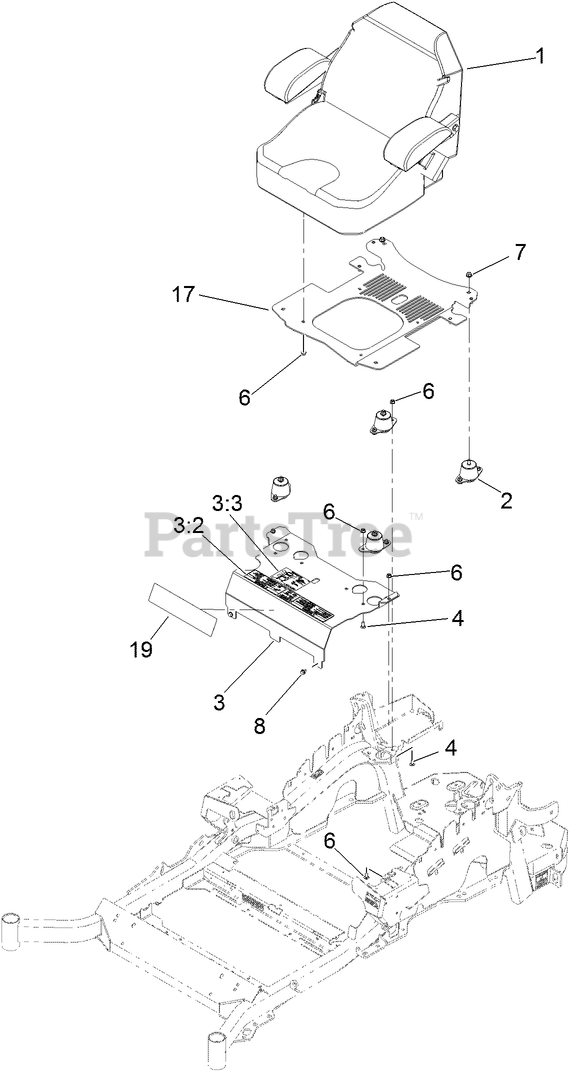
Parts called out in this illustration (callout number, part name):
1	SEAT-STANDARD
2	ISOLATOR-SEAT
3	MOUNT-SEAT
3:2	DECAL-CONSOLE
3:3	DECAL-SERVICE AID
4	SCREW-CARR
6	NUT-HF, NI
7	NUT-HF, NI
8	SCREW
17	SEAT BASE ASM
